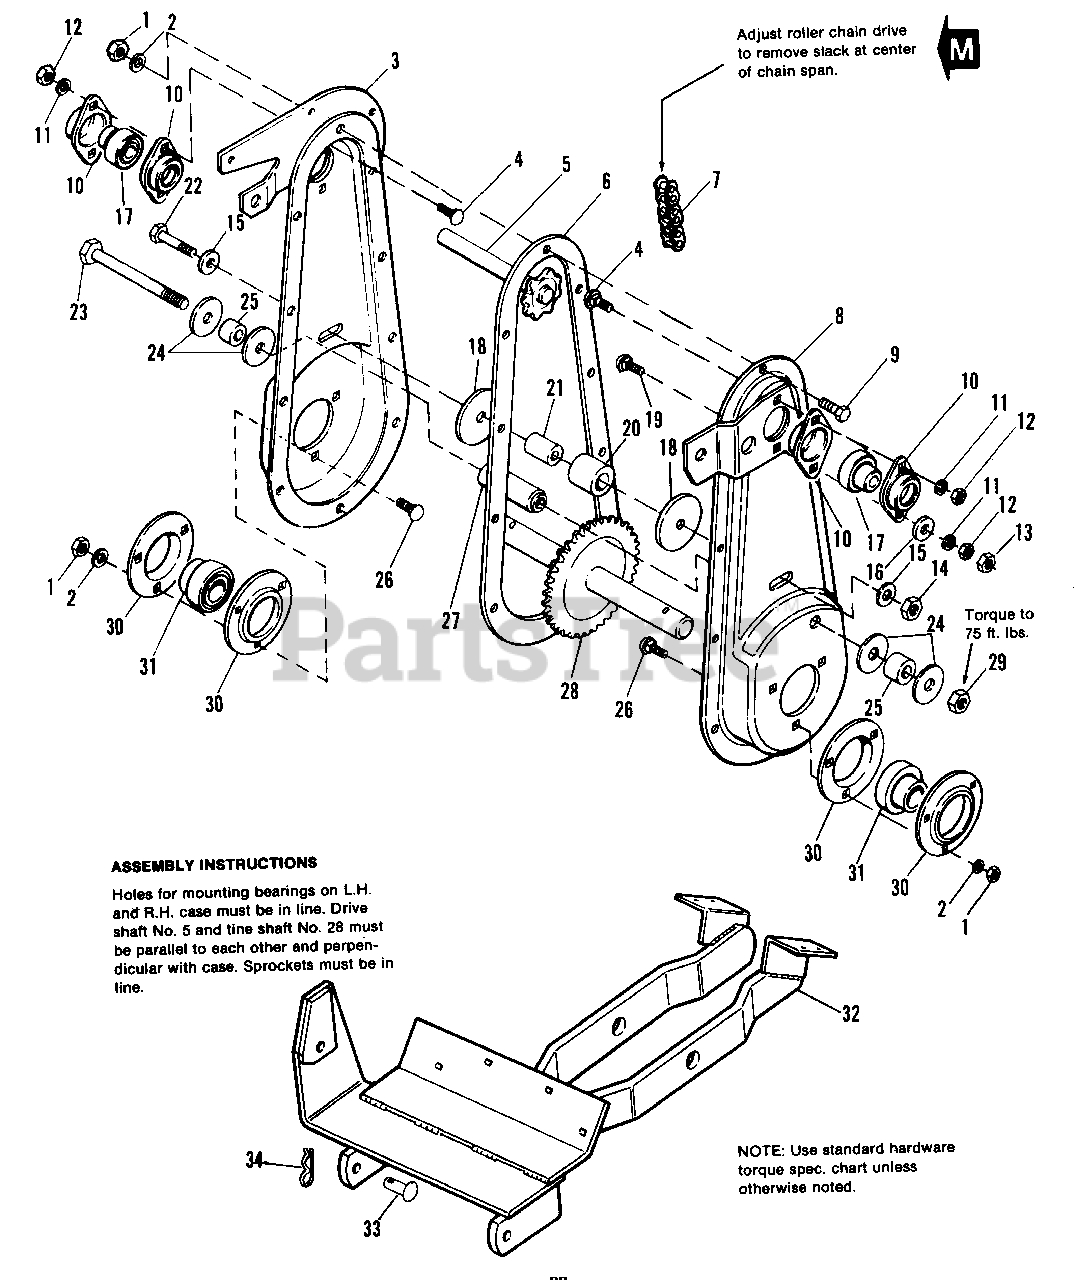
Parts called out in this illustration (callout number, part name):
1	NUT, Hex, Full, 5/16-18
2	LOCKWASHER, 5/16
3	CASE ASSY., Half, R.H.
4	BOLT, Carriage, 1/4-20 x 3/4
5	SHAFT ASSY., Drive
6	GASKET, Case
7	CHAIN, Drive
8	CASE ASSY., Half, L.H.
9	CAPSCREW, Hex, 5/16-18 x 5/8
10	FLANGE, Bearing
11	LOCKWASHER, 1/4
12	NUT, Hex, Full, 1/4-20
13	LOCKNUT, Full, Hex, 1/4-20
14	LOCKNUT, Hex, Full, 3/8-16
15	WASHER, Special
16	WASHER, Flat, 1/4
19	BOLT, Carriage, 1/4-20 x 1-1/4
22	CAPSCREW, Hex, 3/8-16 x 2-1/4
23	CAPSCREW, Hex, 1/2-13 x 5
26	BOLT, Carriage, 5/16-18 x 3/4
27	SPACER, Case
28	SHAFT ASSY., Tine
29	LOCKNUT, Hex, Full, 1/2-13
30	BEARING, Flange
31	BEARING, Cartridge
32	FRAME & HITCH ASSY.
34	CLIP, Hair Pin
